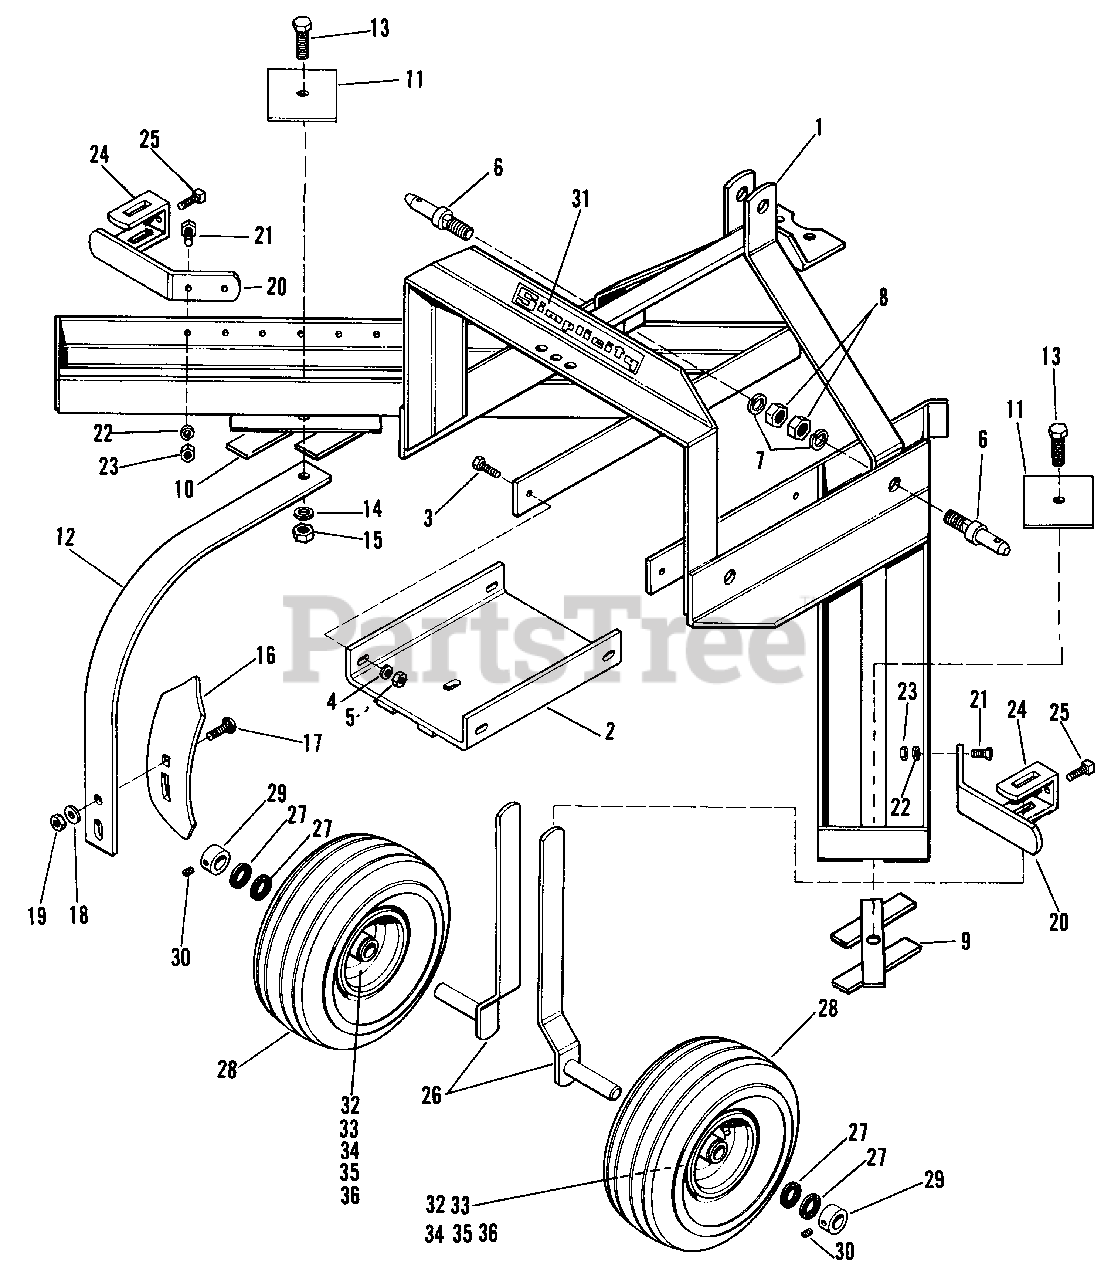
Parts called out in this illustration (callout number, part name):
1	Cultivator Frame
2	Support Plate Assembly
3	Hex Capscrew, 3/8"-16 x 1-1/4"
4	Lock Washer, 3/8"
5	Hex Nut, Full, 3/8"-16
6	Hitch Pins
7	Lock Washer, 5/8"
8	Hex Nut, Full, 5/8"-11
9	R.H. Shank Holder Assy.
10	L.H. Shank Holder Assy.
13	Hex Capscrew, 1/2"-13 x 1-1/2"
14	Lock Washer, 1/2"
15	Hex Nut, Full, 1/2"-13
16	Cultivator Teeth
17	Plow Bolt, 7/16"-14 x 1-1/4"
18	Plain Washer, 7/16"
19	Hex Nut, Full, 7/16"-14
21	Hex Capscrew, 3/8"-16 x 1-1/4"
22	Lock Washer, 3/8"
23	Hex Nut, Full, 3/8"-16
24	Shank Clamp
25	Set Screws, 3/8"-16 x 1"
26	Standard & Spindle Assy.
27	Felt Seal
28	Wheel & Tire Assembly
29	Set Collar
30	Set Screw, 5/16"-18 x 5/16"
32	Tire
33	Tube
34	Bearing
35	Bearing Relief
36	Wheel
